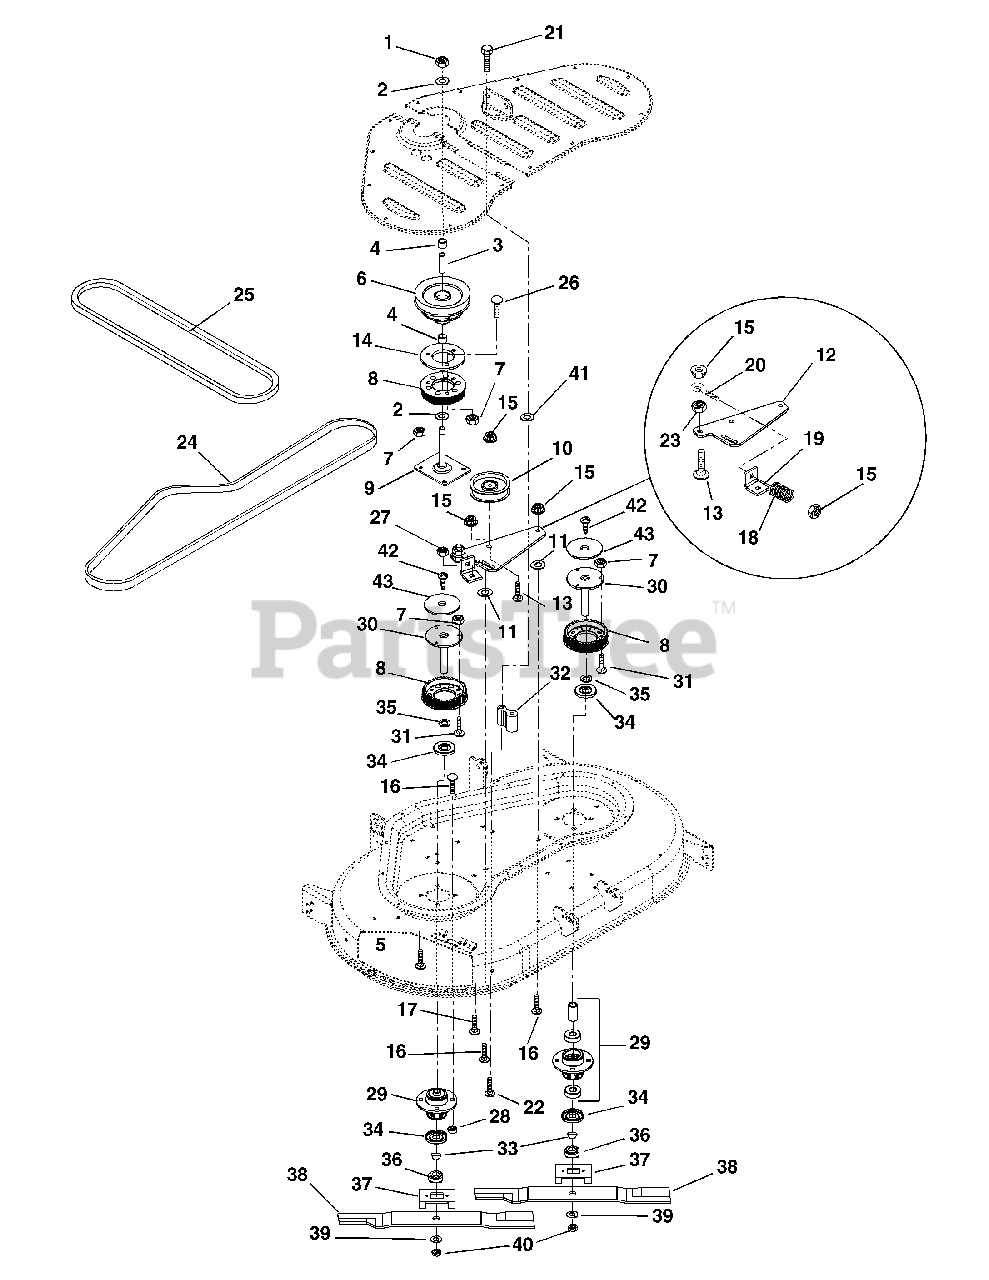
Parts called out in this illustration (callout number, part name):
1	@NUT-LK-NYL .625-18 YWZC
2	WSHR-FL-STL .630X1.005X.062 YZ
3	SPACER, .640X.88X3.634
4	BRG-BALL .625X1.375X.43
5	@BLT-RDHDSQNK .31-18X.75 G5YZ
6	JACKSHAFT (SIERRA)
7	@NUT-LK-TOP-FLG .31-18 YWZC
8	SPROCKET, DRIVE
9	WELDMENT, PLATE MOUNT (SIERRA)
10	PULLEY, IDLER 4.00
11	WSHR-FL-STL .38"X1.5"X.188"
12	ARM, BELT ADJUSTMENT
13	@BLT-RDHDSQNK .38-16X1.75 G5YZ
14	SPACER, SPROCKET
15	@NUT-LK-TOP-FLG .38-16 YWZC
16	@BLT-RDHDSQNK .38-16X1.25 G5YZ
17	@BLT-RDHDSQNK .38-16X.75 G5YZ
18	SG-COMP .187X.56X1.62
19	BRACKET, BELT ADJUSTMENT
20	BLT-EYE .375-16X2.50 YWZC
21	@BLT-HEX .38-16X1.00 GR5 YWZC
22	BLT-SERHFWH .375-16X1.25 YWZC
23	@NUT-LK-NYL .38-16 YWZC
24	COG-BELT X8M
25	V-BELT, HA-RAW EDGE
26	@BLT-RDHDSQNK .31-18X1.25 G5YZ
27	@NUT-LK-CTR-JAM .375-16 YWZC
28	@NUT-LK-TOP-FLG .38-16 YWZC
29	ASSEMBLY, SPINDLE HOUSING
30	WELDMENT, SPINDLE SHAFT
31	@BLT-RDHDSQNK .31-18X1.00 G5YZ
32	SUPPORT, LIFT BRACKET
33	KEY-WDRF .188X.625X.31 SAE9MOD
34	BEARING SLINGER
35	WSHR-FL-STL .755X1.25X.125 YZ
36	HUB, RETAINER
37	TRAY, BLADE
38	BLADE, 22"
39	@WSHR-LK .75X.188 REG YWZC
40	NUT-JAM .75-10 YWZC
41	@WSHR-FL-STL.38X.875X.083 YWZC
42	SCR-TAP .25-20X.75 HWH TR YWZ
43	RETAINER, BELT
